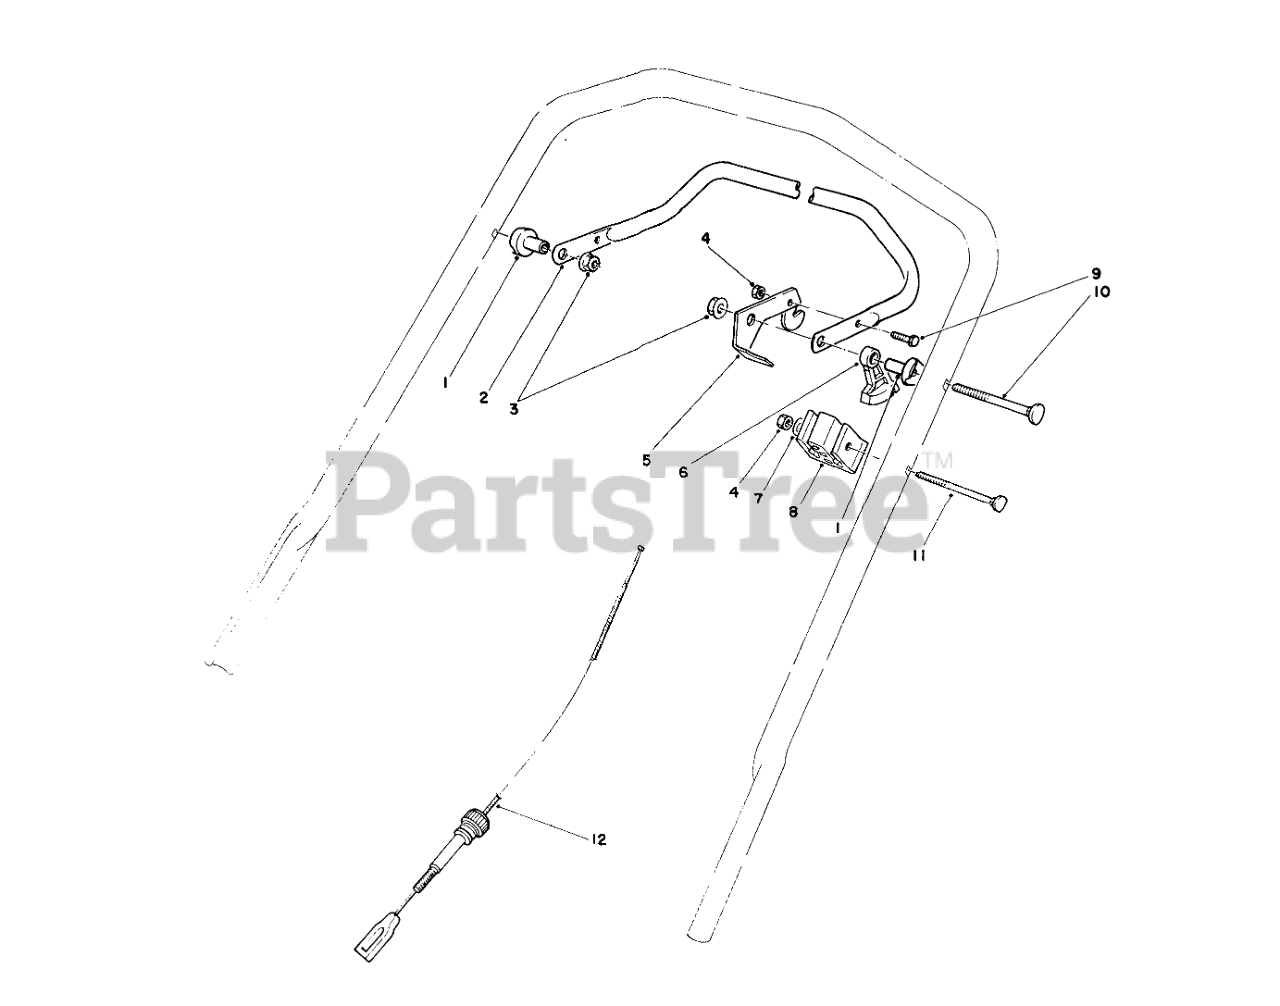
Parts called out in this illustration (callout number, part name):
1	SPACER-SUPPORT
2	Bar-Control
3	NUT-LOCK, NI
4	NUT-LOCK, NI
5	LEVER-CONTROL
6	LEVER-TRACTION
7	WASHER-FLAT
8	SUPPORT-CABLE
9	SCREW-HH
10	5/16-18 X 2 HNDLE SCREW
11	HANDLE SCREW
12	CABLE-TRACTION
